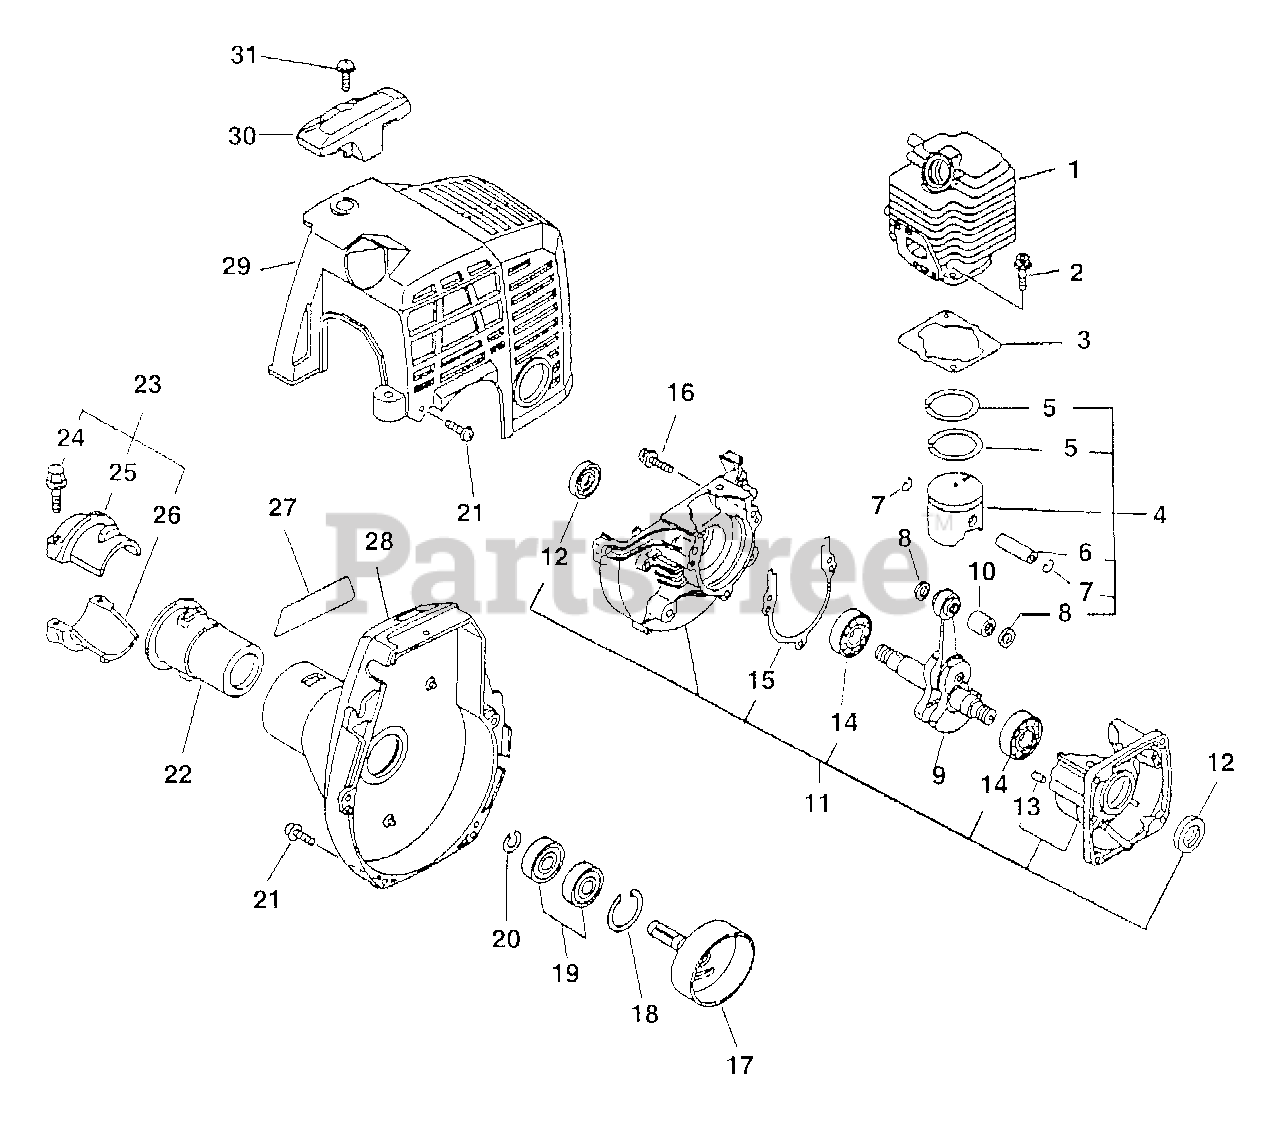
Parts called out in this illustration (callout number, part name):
1	CYLINDER/PISTON KIT
2	BOLT 5×22
3	GASKET, CYLINDER
4	PISTON KIT
5	RING, PISTON
6	PIN, PISTON 8
7	RING, SNAP
8	WASHER, THRUST
9	CRANKSHAFT ASSY
10	BEARING, NEEDLE
11	CRANKCASE KIT
12	SEAL, OIL 12
13	PIN, LOCATING 4
14	BEARING, BALL - 6201 C3
15	GASKET, CRANKCASE
16	BOLT 5×28
17	DRUM, CLUTCH
18	RING, SNAP 28
19	BEARING, BALL 6001
20	RING, RETAINING - 12
21	BOLT 4×16
22	CUSHION Ø25
23	RETAINER KIT
24	BOLT - 5×25
25	HOLDER, MAIN PIPE - UPPER
26	HOLDER - LOWER
27	LABEL, MODEL
28	COVER ASSY, FAN
29	COVER, ENGINE
30	GUARD, TOP
31	SCREW 5×16
